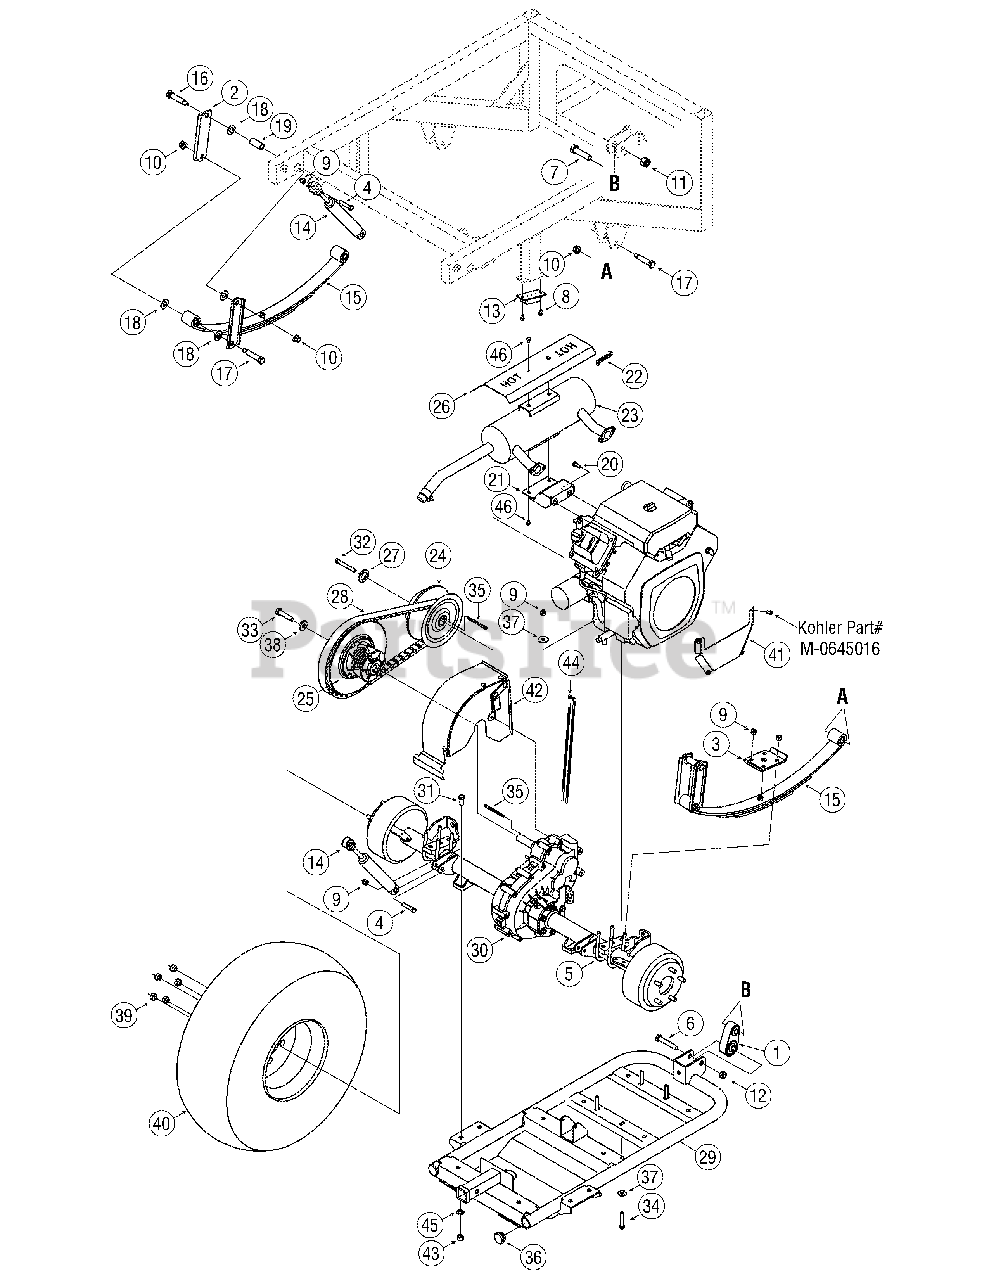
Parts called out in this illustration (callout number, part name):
1	Link Assembly
2	Plate, Shackle
3	Bracket, Spring Leaf
4	Hex Screw, 3/8-16 x 1.75
5	U-Bolt 3/8-16
6	Hex Screw, M12-1.75
7	Hex Screw, 5/8-11 x 2.5
8	Screw, Self Tapping 1/4-20
9	Locknut, Nylon, 3/8-16
10	Hexlock Nut
11	Hexlock Nut, Flange, 5/8 -11
12	Hexlock Nut, M12 x 1.75
13	Bumper, Suspension
14	Shock Absorber, 2.50 Stroke
15	Spring, Leaf 4 x 2
16	Shoulder Screw, .550 x 2.29
17	Shoulder Screw, .550 x 2.13
18	Bearing, .56 ID x 1.25 OD x .06
19	Bush, .75 OD x .562 ID x 1.75 LG
20	Screw, M8 x 1.25:20
21	Brkt., Muffler
22	Spring, Ext., .375 Dia. X 3.18 Lg.
23	Muffler, Kohler
24	Clutch Assembly, Engine
25	Clutch Assembly, Transmission
26	Shield, Heat, Kohler
27	Spacer, .39 x 1.0
28	Belt, Cogged
31	Hex Screw, 7/16-20 x 1.0
32	Hex Screw,3/8-24 x 3.00
33	Hex Screw, 1/2-20 x 2.25
34	Hex Screw,3/8-16 x 2.00
35	Key, Square 1875 x 3.25
36	Plug, Tube
37	Washer, Flat, .406 x 1.00 x .105
38	Wash, Flat, .531 ID x 1.25 X 1.00
39	Lug Nut, 7/16-14
40	RH Wheel Assembly, 25 x 11 x 10
40	LH Wheel Assembly, 25 x 11 x 10
45	Washer, Flat, .469 x .875 x .105
46	Screw, M6-1 x 10mm
